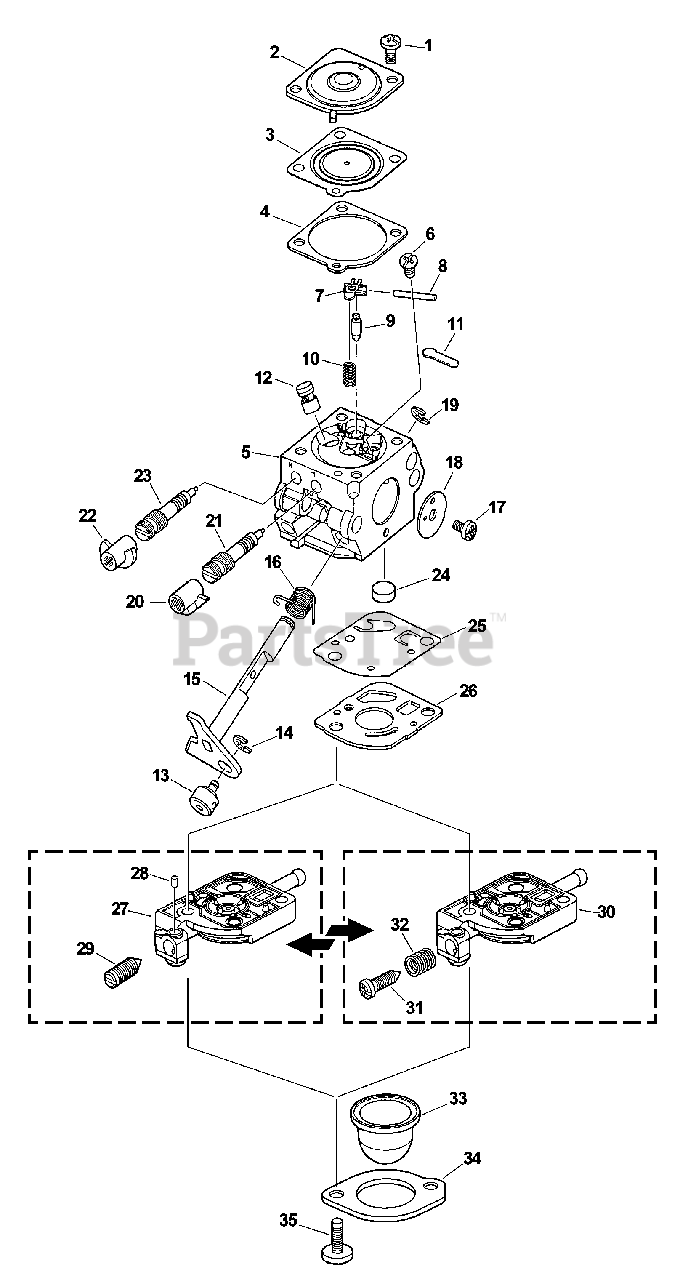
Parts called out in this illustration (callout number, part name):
2	COVER, METERING DIAPHRAGM
3	DIAPHRAGM, METERING
4	GASKET, METERING
5	BODY, CARBURETOR
7	LEVER, METERING
8	PIN, METERING LEVER
9	VALVE, INLET NEEDLE
10	SPRING, METERING LEVER
11	PLUG, WELCH
12	NOZZLE, CHECK VALVE
15	SHAFT, THROTTLE
16	SPRING, THROTTLE RETURN
18	VALVE, THROTTLE
20	CAP, LIMITER - WHITE
21	NEEDLE, LOW SPEED
22	CAP, LIMITER - RED
23	NEEDLE, HIGH SPEED
24	STRAINER
27	BODY ASSY, PURGE
28	PIECE, FRICTION
29	SCREW, IDLE ADJUST
30	BODY ASSY, PURGE
31	SCREW, THROTTLE ADJUST
33	BULB, PURGE
34	RETAINER
